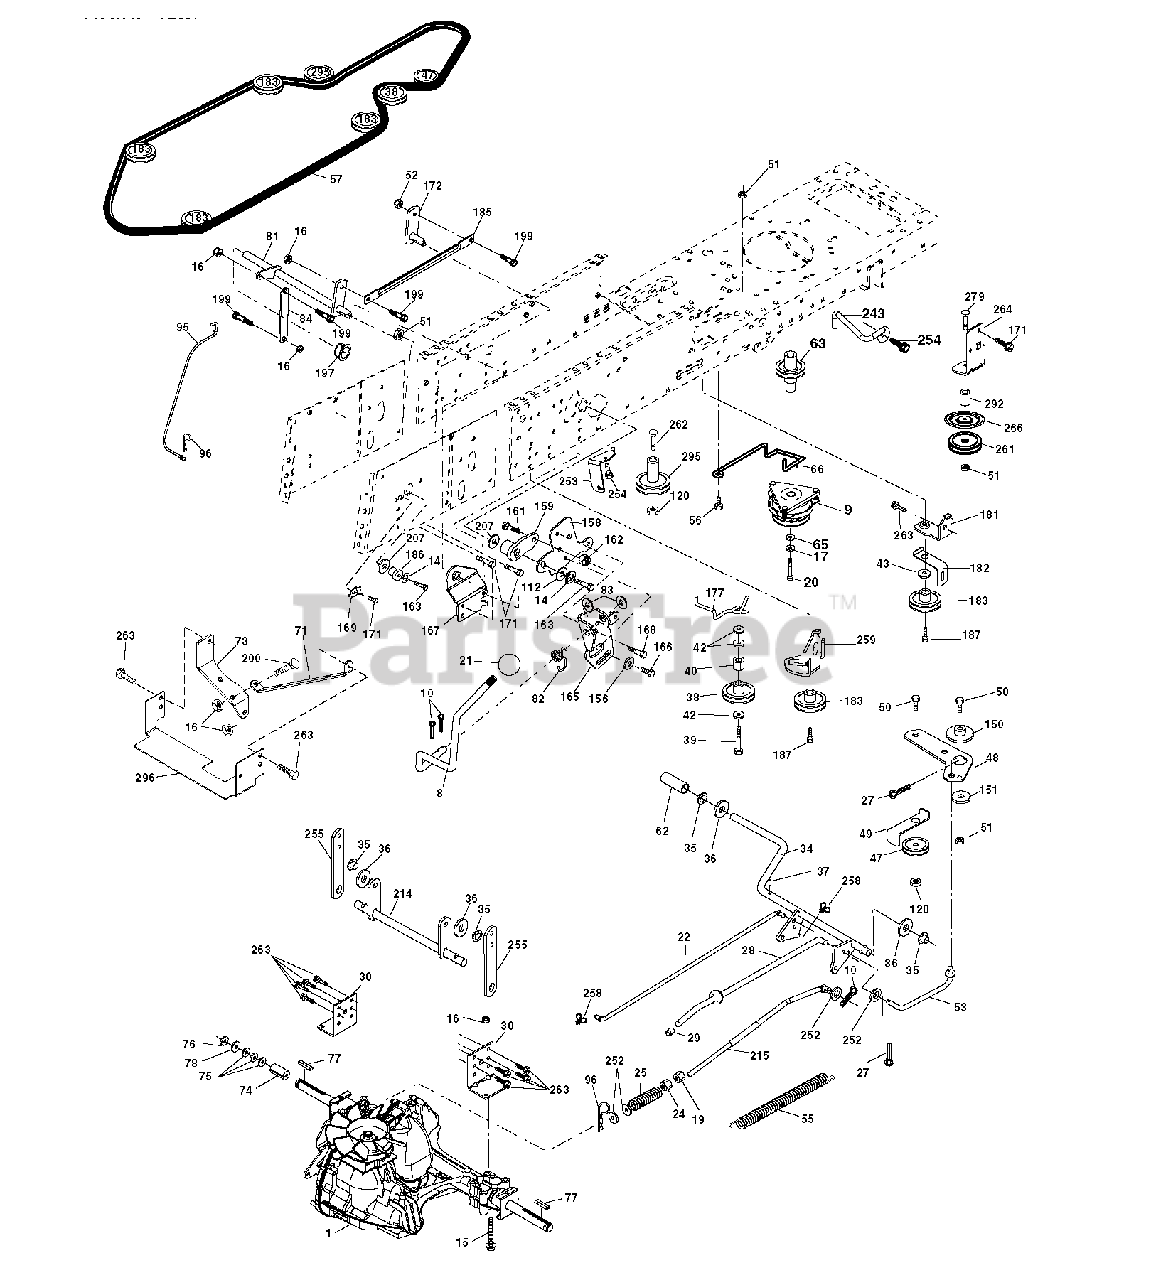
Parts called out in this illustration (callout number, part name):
8	ROD SHIFT FENDER ADJUST LT
10	PIN COTTER
14	LOCKWASHER
15	BOLT HEX 5/16-18 GR 5
16	NUT.71038.31-18.HEX.NYLOCK
19	NUT
20	BOLT HEX 7/16-20X4-1/4"
21	PISTOL KNOB
24	NUT
27	COTTER PIN
28	ROD, PARKING BRAKE
29	PLUNGER CAP
30	BRKT, TRNSXLE MNT 20"
34	SHAFT, FOOT PEDAL
35	BEARING.NYLON
36	WASHER LT
37	DRIVE PIN
38	PULLEY.FLAT
42	WASHER
47	IDLER PULLEY
48	BELLCRANK, CLUTCH
49	RETAIN BELT
50	BOLT.3/8-16X1.50
51	LOCKNUT
52	LOCKNUT
53	LINK.CLUTCH.7.66.2005
55	SPRING, RETURN LT
56	SCREW.3/8-16
62	PEDAL COVER T
65	LOCKWASHER
66	KEEPER BELT ENGINE
71	STRAP TORQUE LH HYDRO
73	STRAP TORQUE RH HYDRO
74	SPACER AXLE
76	E-RING LT
77	SQUARE KEY
81	SHAFT ASSY
82	SHIFT SPRING
83	WASHER
96	RETAINER M
112	WASHER LT
120	NUT LOCK FLG 3/8-16 UNC
150	BUSHING.BELLCRANK.GRD.DR
151	WASHER 12/32X2X10GA
156	WASHER.SRRTD.5/16
158	BRACKET
159	HUB.SHIFT
161	BOLT
162	NUT.CROWNLOCK.1/4
165	RP BRACKET
167	BRACKET
168	BOLT.SHOULDER.5/16-18X
169	PLATE.FASTENING.CROSS.SHAFT
187	BOLT.5/16-18X1.25
197	NYLINER SNAP 5/8" ID
199	BOLT SHOULDER 5/16-18 UNC
200	BOLT
207	WASHER NYL
243	BRACKET, ANTI-ROTATION
254	SCREW 3/8-16X1
258	CLIP RETAINER
261	FLAT IDLER PULLEY
263	SCREW, 3/8-16X3/4
279	BOLT
295	PULLEY IDLER COMPOSITE
